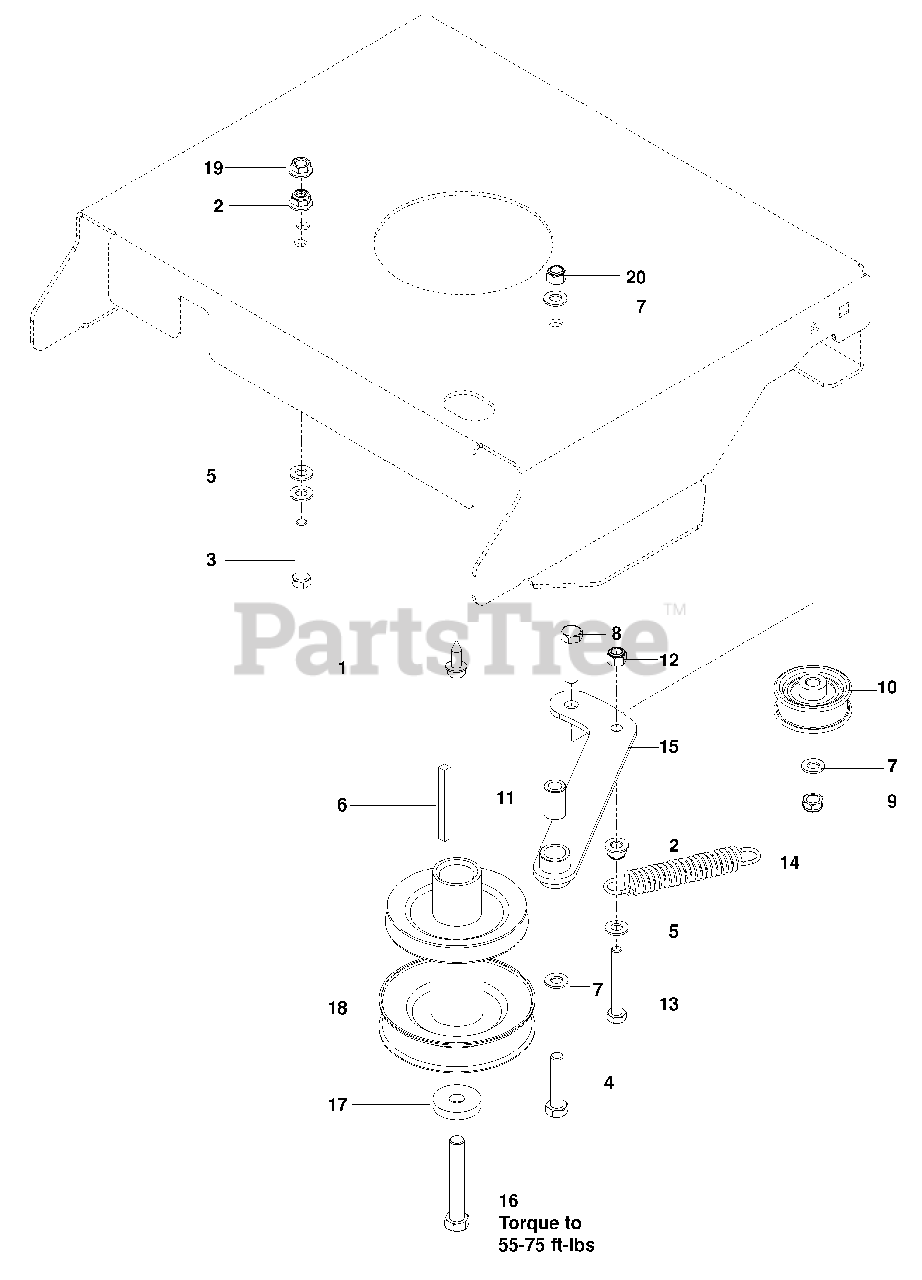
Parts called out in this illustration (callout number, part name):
1	HHFS 3/8-16 x 1 THD FRM
2	NUT 5/16-18 FLANGE NYLOC
3	HCS 5/16-18 x 2
4	HCS 3/8-16 x 2
5	WASHER 5/16 SAE FLT
6	KEY 1/4 SQ x 2 1/2 LG
7	WASHER 3/8 FLT STD
8	HCS 3/8-16 x 1 1/2
9	NUT 3/8-16 HEX JAM NYLOC
10	PULLEY, IDLER
11	BUSHING, METAL
12	NUT 5/16-18 HEX NYLOC
13	HCS 5/16-18 x 2 1/4
14	SPRING 3 1/2
16	HCS 7/16-20 x 2 3/4
18	PULLEY, ENGINE
19	NUT 5/16-18 HEX WHIZLK
20	NUT 3/8-16 HEX NYLOC
